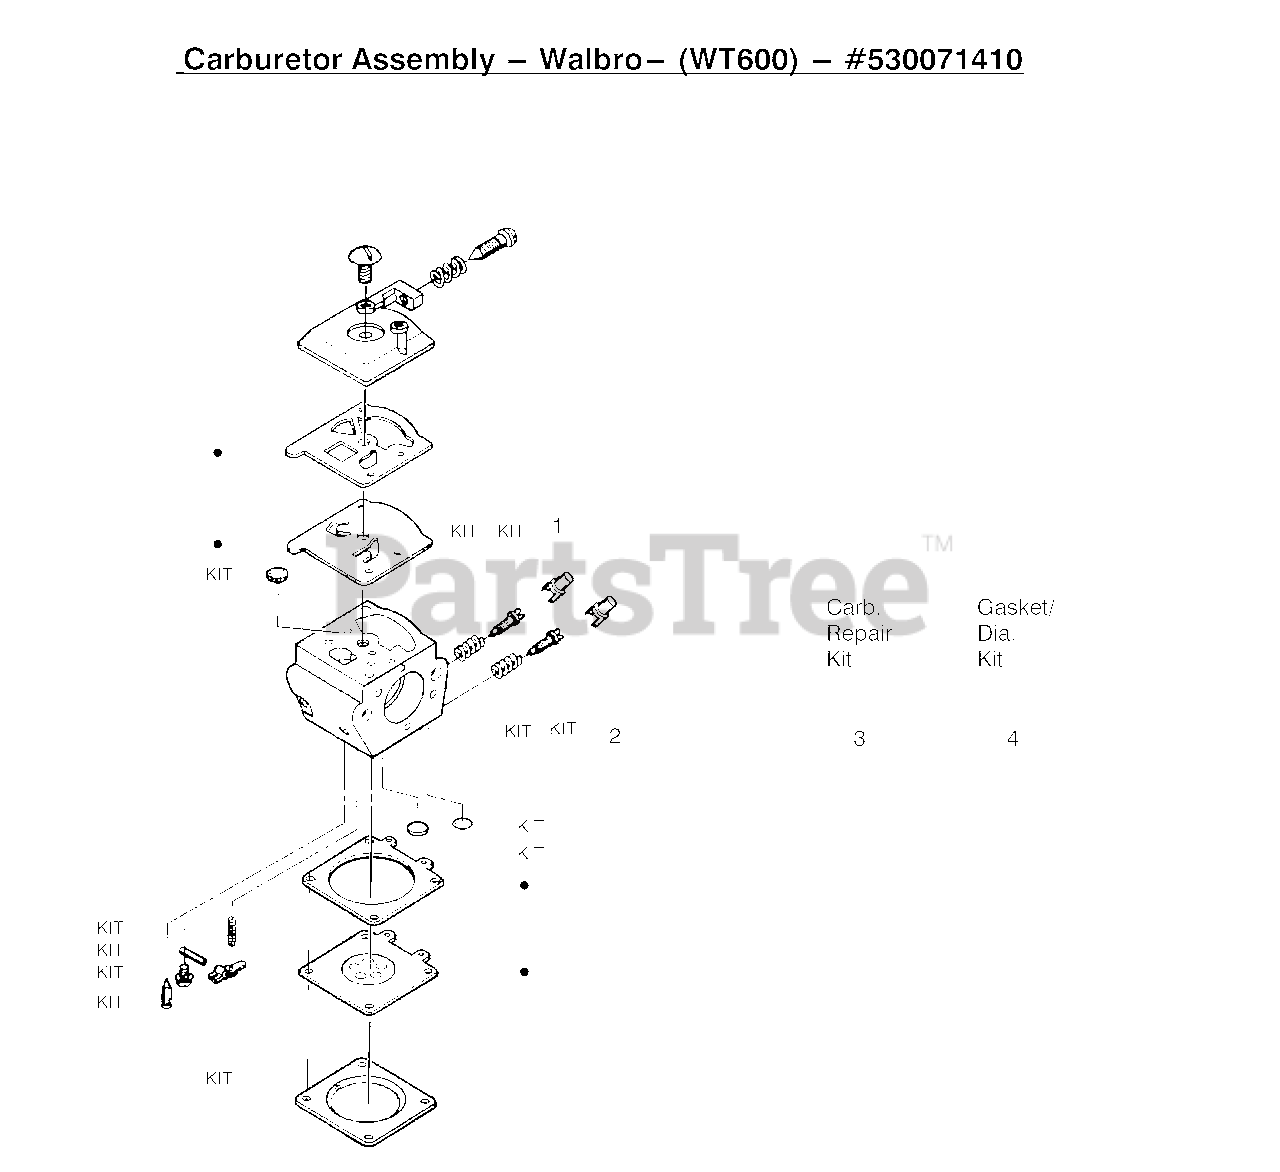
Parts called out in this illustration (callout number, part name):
1	Limiter Cap-High
2	Limiter Cap-Low
3	Carburetor Repair Kit
4	Gasket Diaphragm Kit
